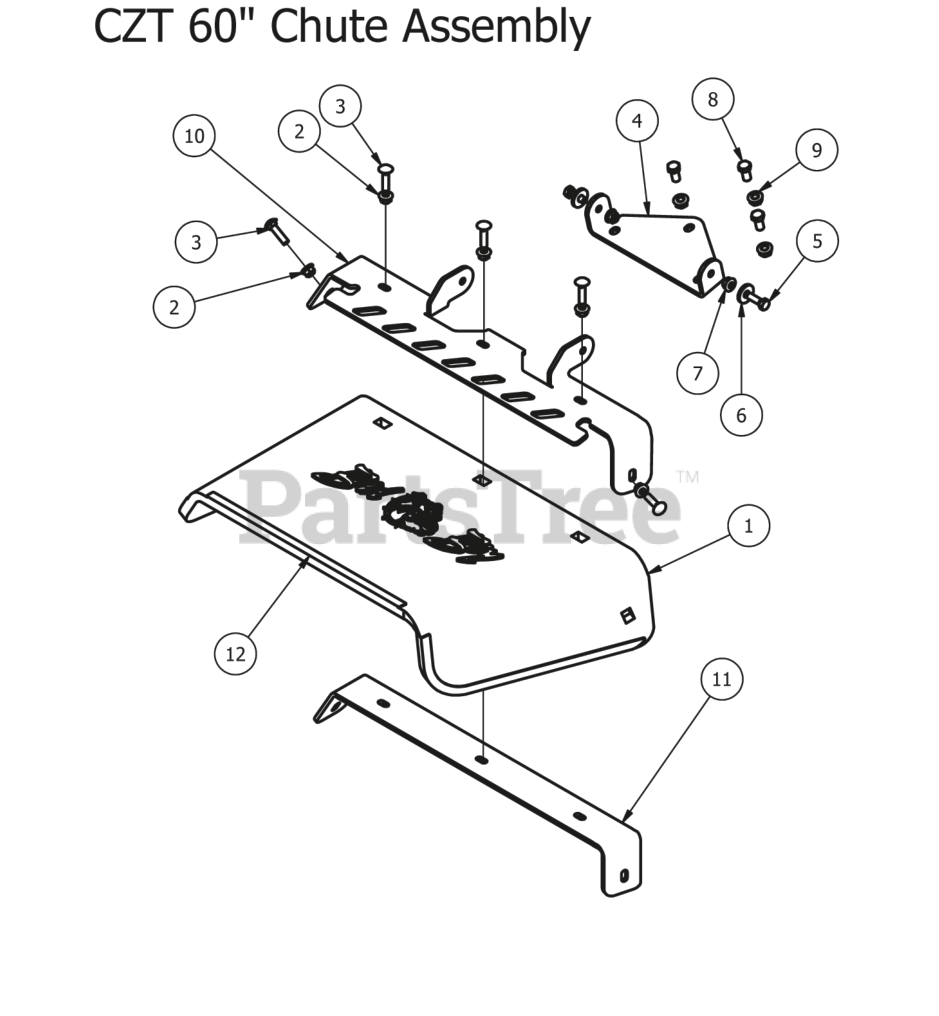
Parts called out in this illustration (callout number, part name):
1	Rubber Discharge Chute (Rubber Only)
2	5/16" Nylon Flange Nut
3	5/16" x 1 1/4" Carriage Bolt
4	Discharge Chute Hanger (deck mounted)
5	5/16" x 1" Bolt
6	.360 ID Plastic Washer
7	5/16" Nylon Flange Nut
8	3/8" x 3/4" Hex Bolt
9	3/8" Flange Nut
10	60" Upper Hanger Plate
11	60" Lower Hanger
12	60" Rubber Discharge Assembly Components 1,2,3,10,11
